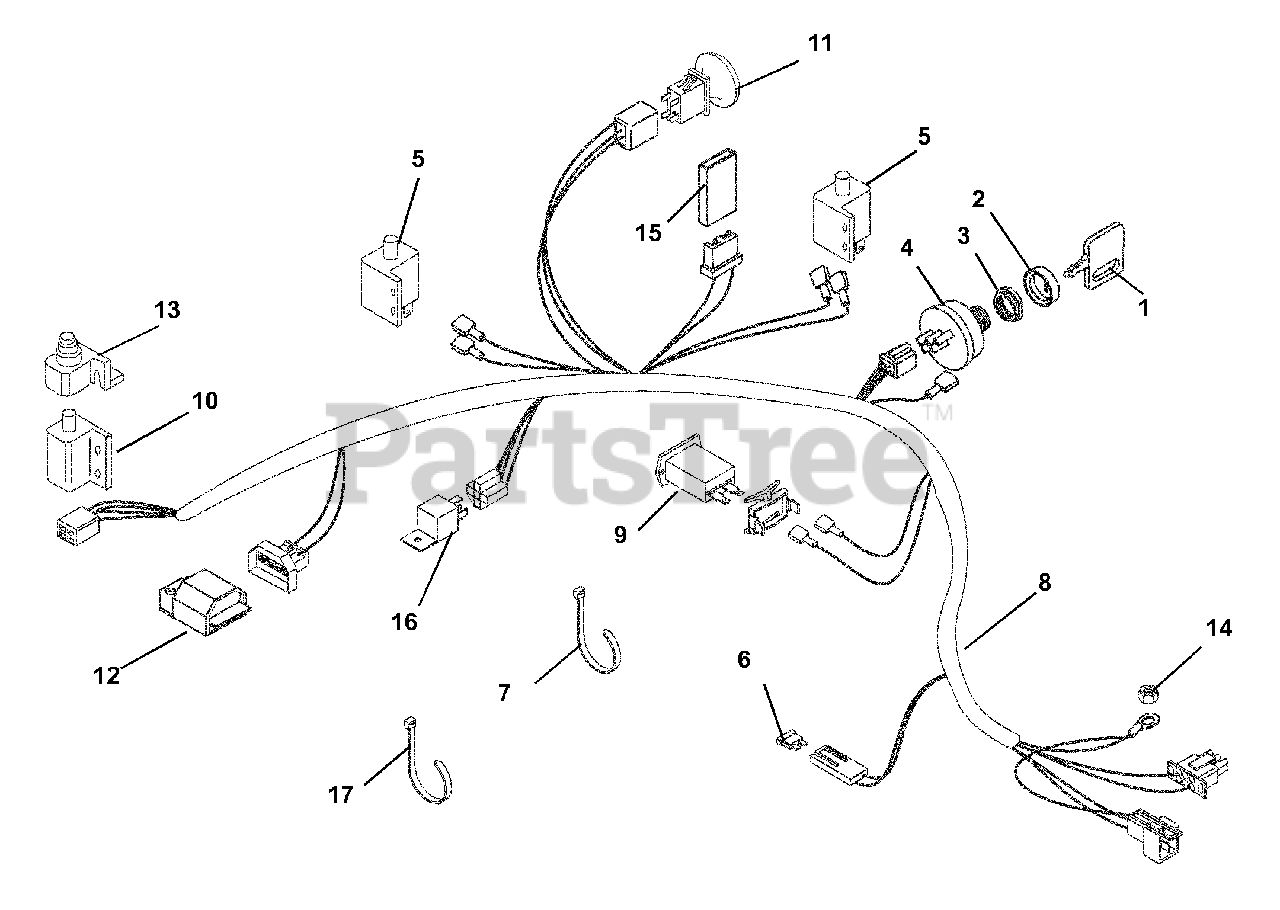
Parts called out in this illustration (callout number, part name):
1	Key, with Cap
2	Cap, Ignition Switch
3	Nut, Panel .562-24
4	Key Switch
5	Switch, Double Pole N.O./N.O.
6	Fuse, 25 AMP
7	Tie Wrap, Black
8	Wire Harness, Hydro Recoil-Pro Steer
9	Hour Meter, Quartz
10	Switch, Interlock
11	Switch, PTO- NMIR
12	Module, Interlock Recoil
13	Boot, Rubber
14	Nut, Locking Top Flange .31-18
15	Diode, Connector Shell
16	Relay
17	Tie Wrap
